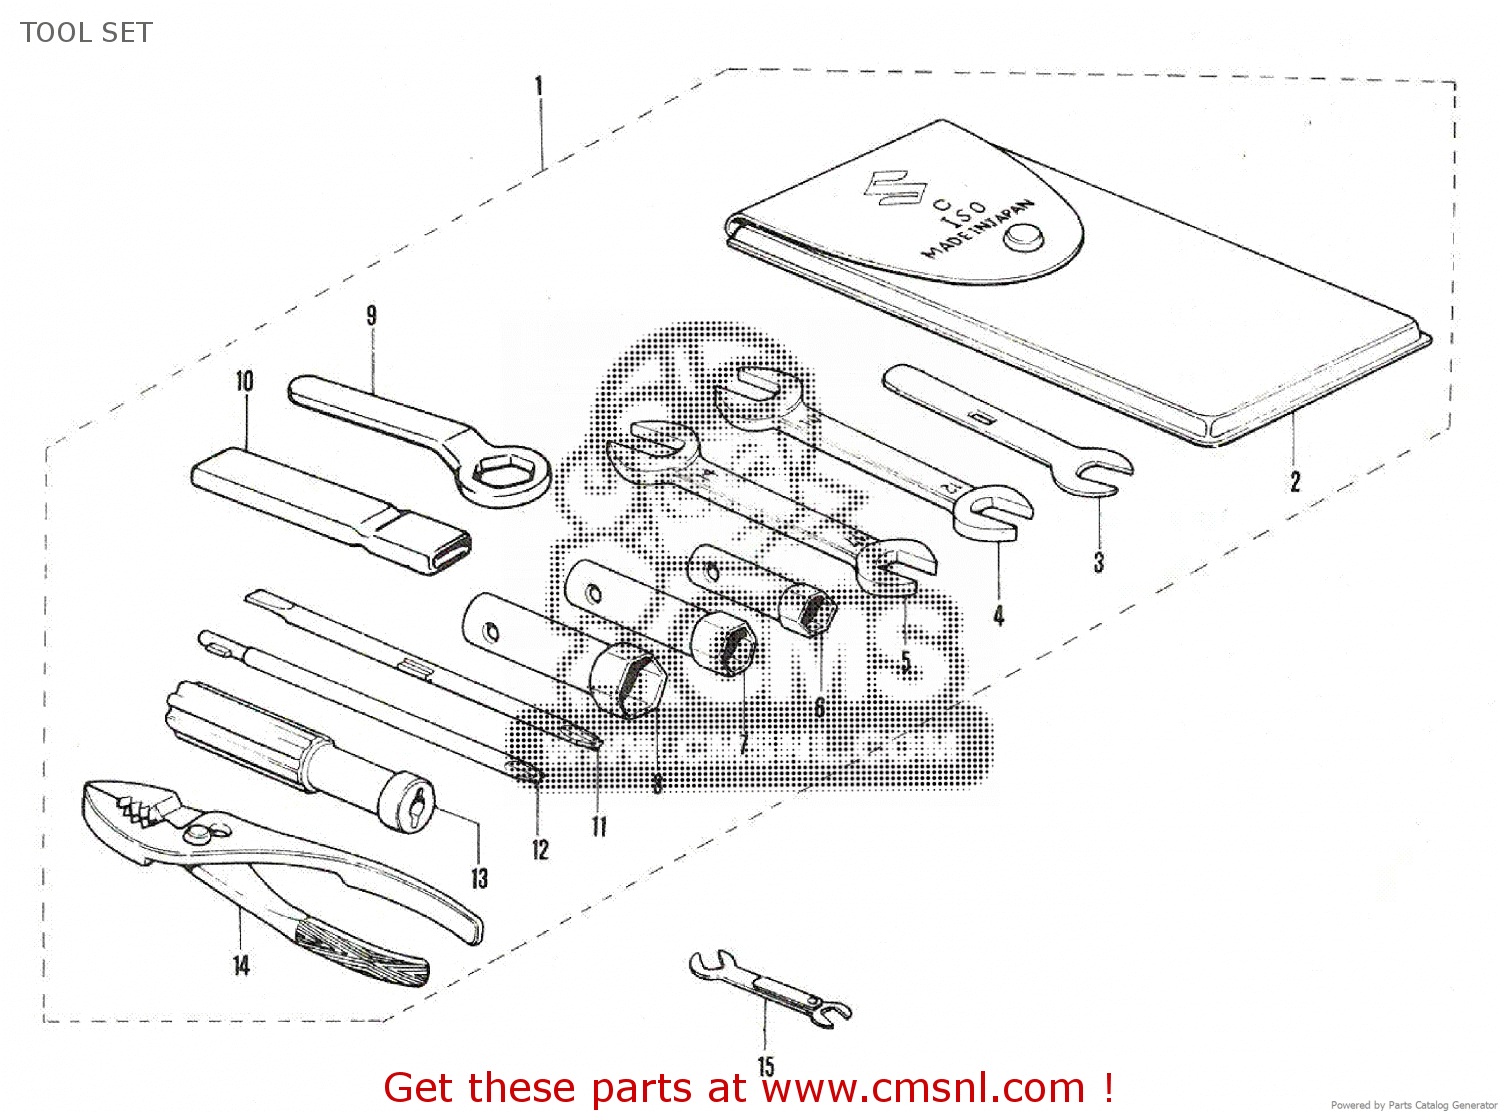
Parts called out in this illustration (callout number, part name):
1	TOOL SET
2	TOOL BAG
3	8 OPEN END WRENCH
4	10X12MM OPEN END WRENCH
5	14X17MM OPEN END WRENCH
6	10MM BOX WRENCH
7	14MM BOX WRENCH
8	21MM BOX WRENCH
9	22MM OFFSET WRENCH
10	WRENCH HANDLE
11	COMBINATION SCREW DRIVER
12	CROSS SCREW DRIVER
13	GRIP, SCREW DRIVER R,J,K,L,M
14	COMBINATION PLIERS
15	WRENCH, CONTACT POINT
